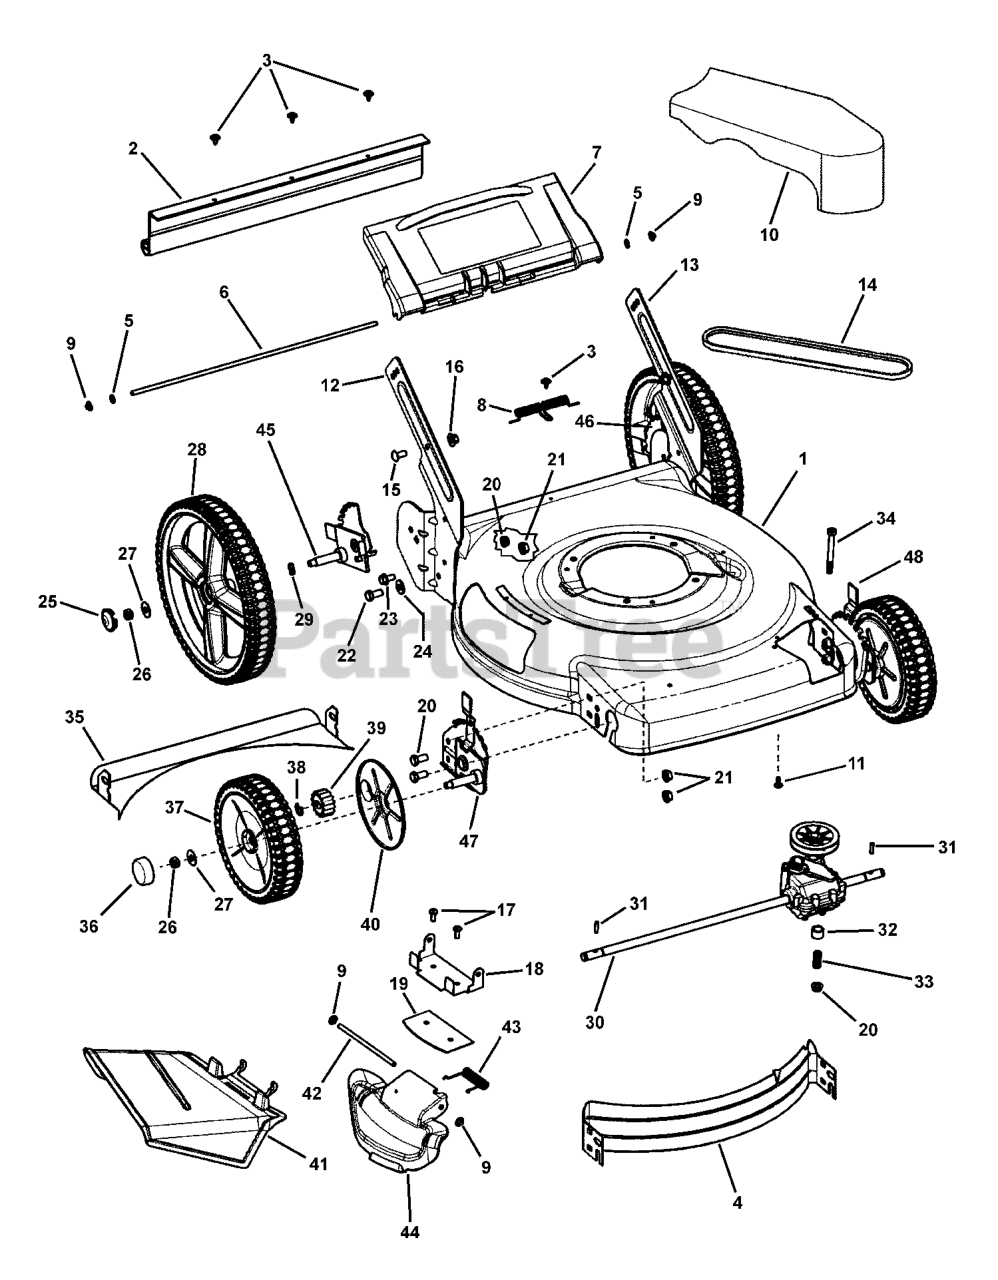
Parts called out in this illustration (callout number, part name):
1	DECK, 22 WALK, 3-N-1
2	GUARD, REAR 22 HW (19-1/2 long)
3	HWST, 10-24X.50 SEMS
4	BAFFLE, FRONT, 22 WBM
5	CAP, RETAINER
6	ROD, PIVOT, REAR DOOR
7	DOOR, REAR DISCHARGE, 22 WALK MOWER
8	SPRING, TORSION, REAR DOOR, 22 WBM
9	PUSHNUT, 1/4
10	COVER, BELT 22"
11	SCREW, Round Washer Head Torx, Hi-Lo
14	BELT, DRIVE 22 (3L Section;33.75 effective length)
15	RHSSNB, 5/16-18 X 3/4 GR5 YZ
16	LHCLN, 5/16-18 BLACK
17	TORX ST, 1/4-20 X 11/16
18	BRACKET, CHUTE
19	PLATE-MULCH, 22 RB SCOTT'S
20	NUT, HEX FLANGE LOCK, 5/16-18 NC
21	HFLN, 3/8-16, BRIGHT ZINC
22	HHCS, 3/8-16 X 3/4
23	HFLB, 5/16-18 X 5/8
24	FLW, .375 X .875 X .083 YZ
25	HUBCAP, 12 WHEEL, BLACK
26	HCLN, 3/8-16 YZ
27	WASHER, FLAT, 1 OD X .387 ID
28	WHEEL, 12X 2 IDLE, W/DB TRD, BRUTE YELLOW
29	WASHER, .531 X .781 3-WAVE
30	TRANSMISSION, 22 WBM SS, FWD
31	PIN, DRIVE, 22 WBM, FWD
32	SPACER, ENGINE
33	SPRING, COMPRESSION
34	BOLT, Hex-Head 5/16-18 X 3.00 P&OIL
35	BAFFLE, REAR, 22 DECK
36	HUBCAP, ROUND, BLACK
37	WHEEL, 8X 2 DRIVE, W/DB TRD, BRUTE YELLOW
38	RETAINING RING
39	GEAR, PINION, 22 WBM, FWD
40	SHIELD, DUST, 22 WBM, FWD
41	CHUTE, SIDE, PLASTIC, BLACK
42	ROD, PIVOT, CHUTE
43	SPRING, TORSION, CHUTE
44	COVER, MULCH, PLASTIC, BLACK
45	ASSY, Height-Of-Cut, RR, 22", 9 Position (shown detached)
46	ASSY, Height-Of-Cut, LR, 22", 9 Position (shown attached)
47	ASSY, Height-Of-Cut, RF, 22", Propelled, 9 Position (shown detached)
48	ASSY, Height-Of-Cut, LF, 22", Propelled, 9 Position (shown attached)
